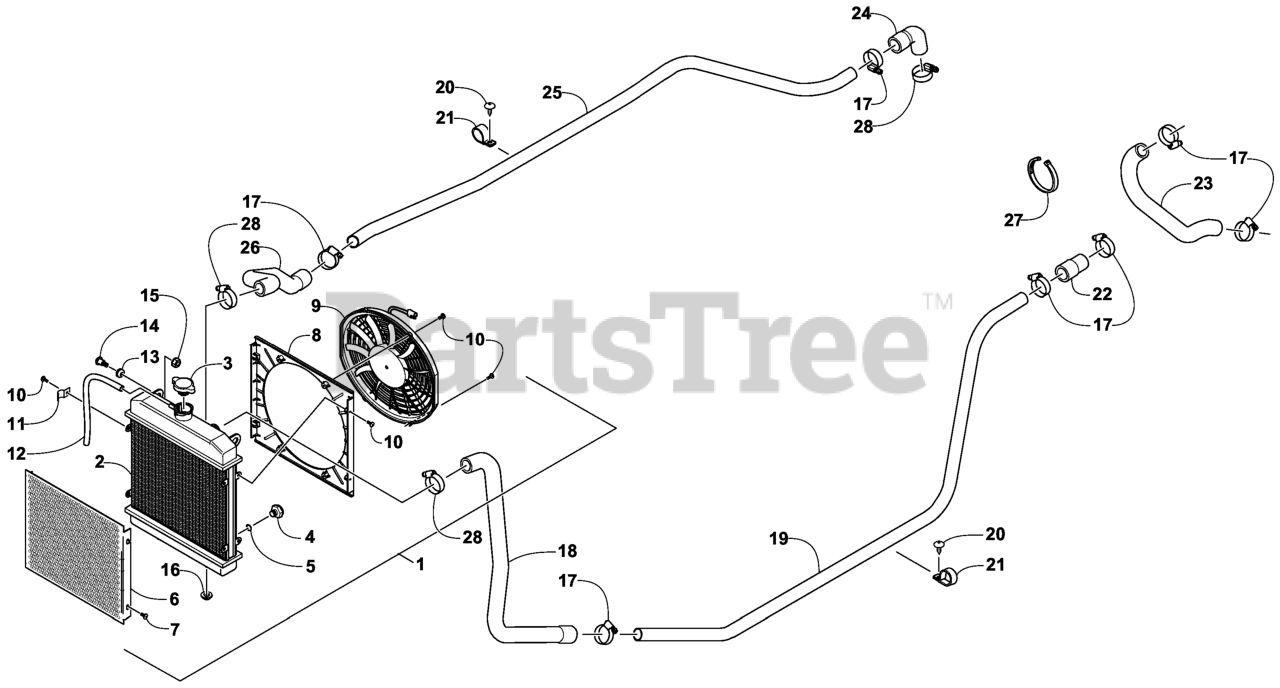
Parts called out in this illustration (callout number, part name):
1	RADIATOR ASM
2	RADIATOR
3	CAP-RADIATOR
4	PLUG-DRAIN, RADIATOR
6	SCREEN-RADIATOR
7	SCREW-TSPRH
8	SHROUD-FAN
9	FAN-RADIATOR
11	CLIP-HOSE
12	HOSE-GAS
13	GROMMET
14	BOLT-SHOULDER
15	NUT-HH, SEMS
16	BUSHING-STEM
17	CLAMP-WORM, HOSE
18	HOSE-RADIATOR, COOLANT UP
19	PIPE-COOLANT, UPPER
20	SCREW-TSTRH, SELFTAP
21	CLAMP-PIPE
22	HOSE-COOLANT
23	HOSE-COOLANT, REAR
24	HOSE-COOLANT, LOWER ENGIN
25	PIPE-COOLANT, LOWER
26	HOSE-RADIATOR, COOLANT LO
27	CABLE TIE
